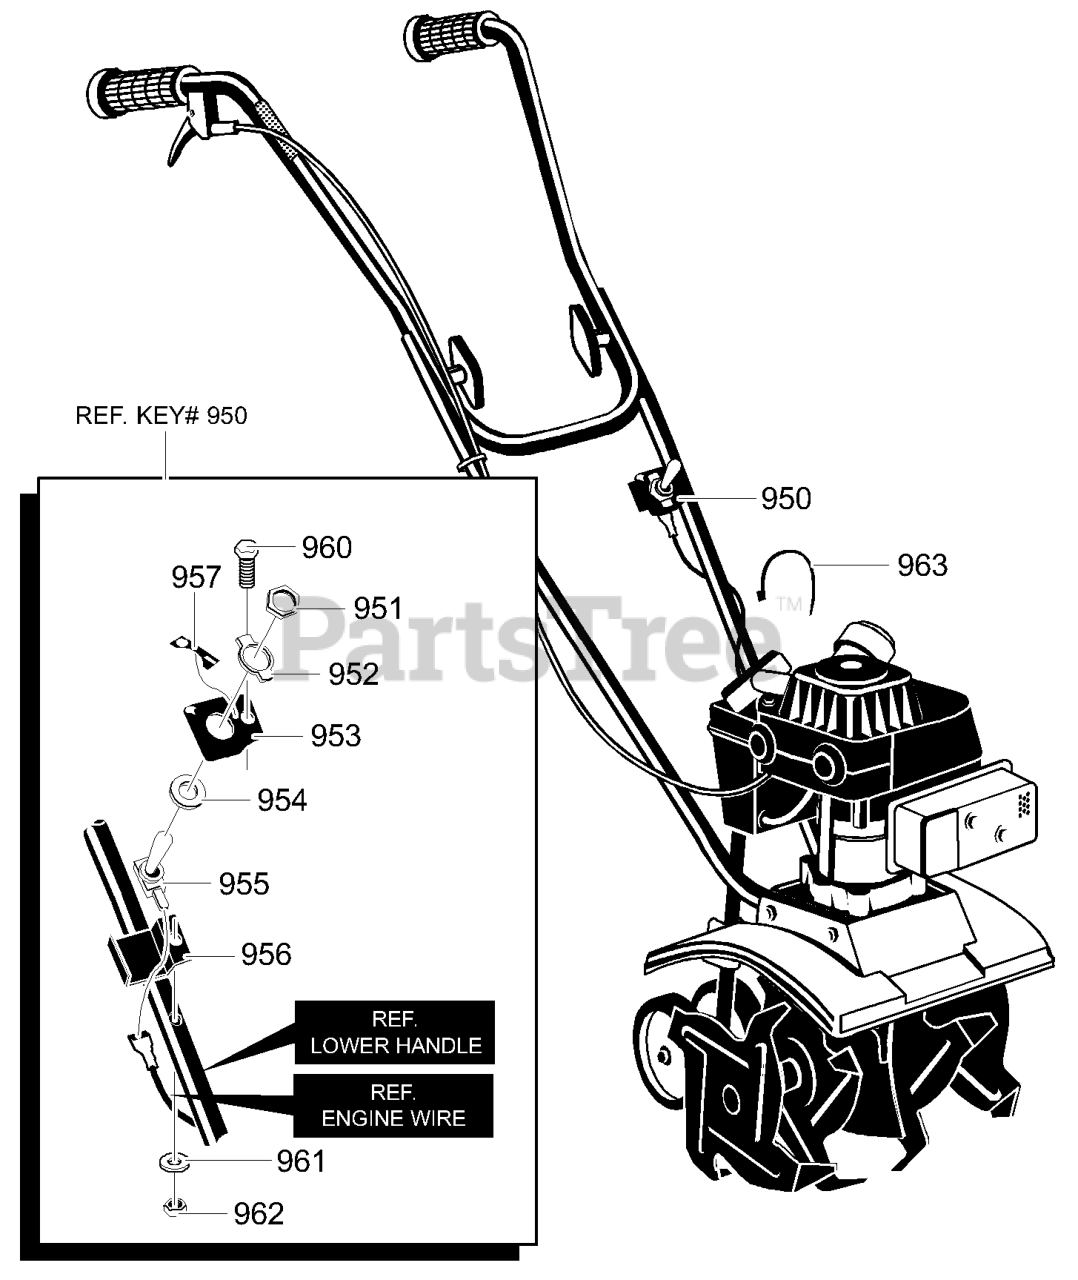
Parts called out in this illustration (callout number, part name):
950	Switch, Assembly
951	Nut, Mtg. 15/32
952	Plate, Indicator
953	Bracket, Mounting -Top
954	Lockwasher
955	Switch
956	Bracket, Mounting -Bottom
957	Decal, ON/OFF
960	Screw
961	Washer
963	Tie, Cable
